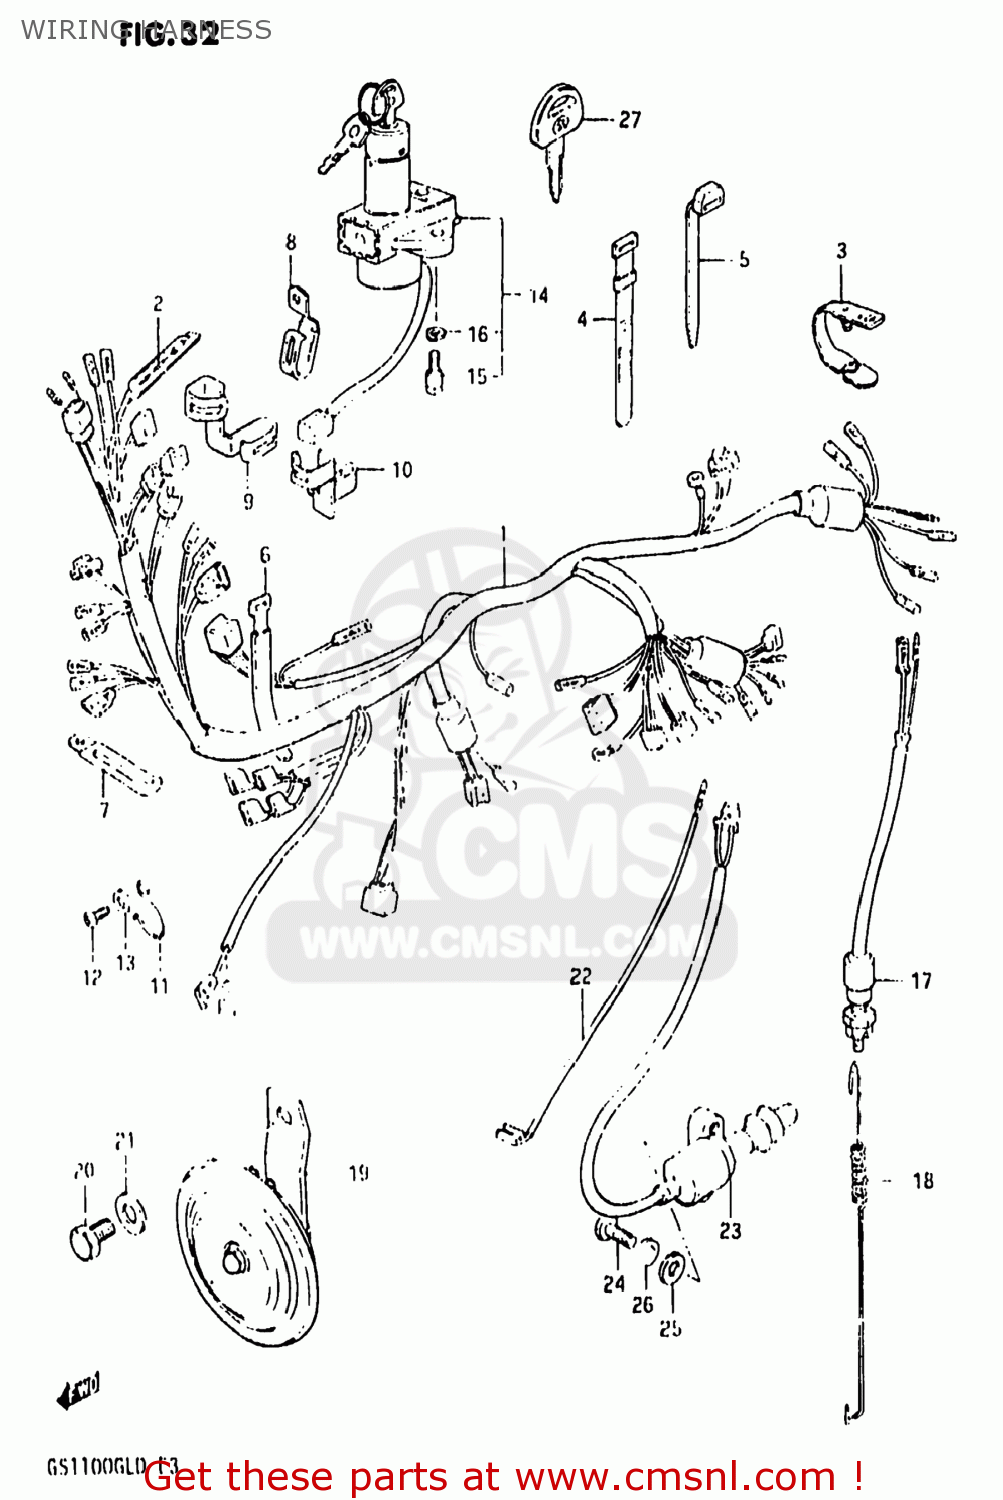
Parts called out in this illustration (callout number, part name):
1	HARNESS,WIRING
2	DIODE
3	CLAMP,L:88
4	CLAMP
5	CLAMP(L:125)
6	CLAMP
7	CLAMP
8	CLAMP,WIRING HARNESS
9	CLAMP,WIRING HARNESS
10	CLAMP,WIRING HARNESS
11	GUIDE,WIRING HARNESS
12	SCREW 6X12
13	WASHER
14	SWITCH ASSY,IGNITION
15	BOLT
16	LOCK WASHER
17	SWITCH ASSEMBLY,STOP LAMP
18	SPRING
19	HORN ASSEMBLY
20	BOLT 8X12
21	WASHER
22	WIRE
23	SWITCH ASSEMBLY,SIDE STAND
24	BOLT
25	WASHER
26	LOCK WASHER
27	KEY,BLANK
